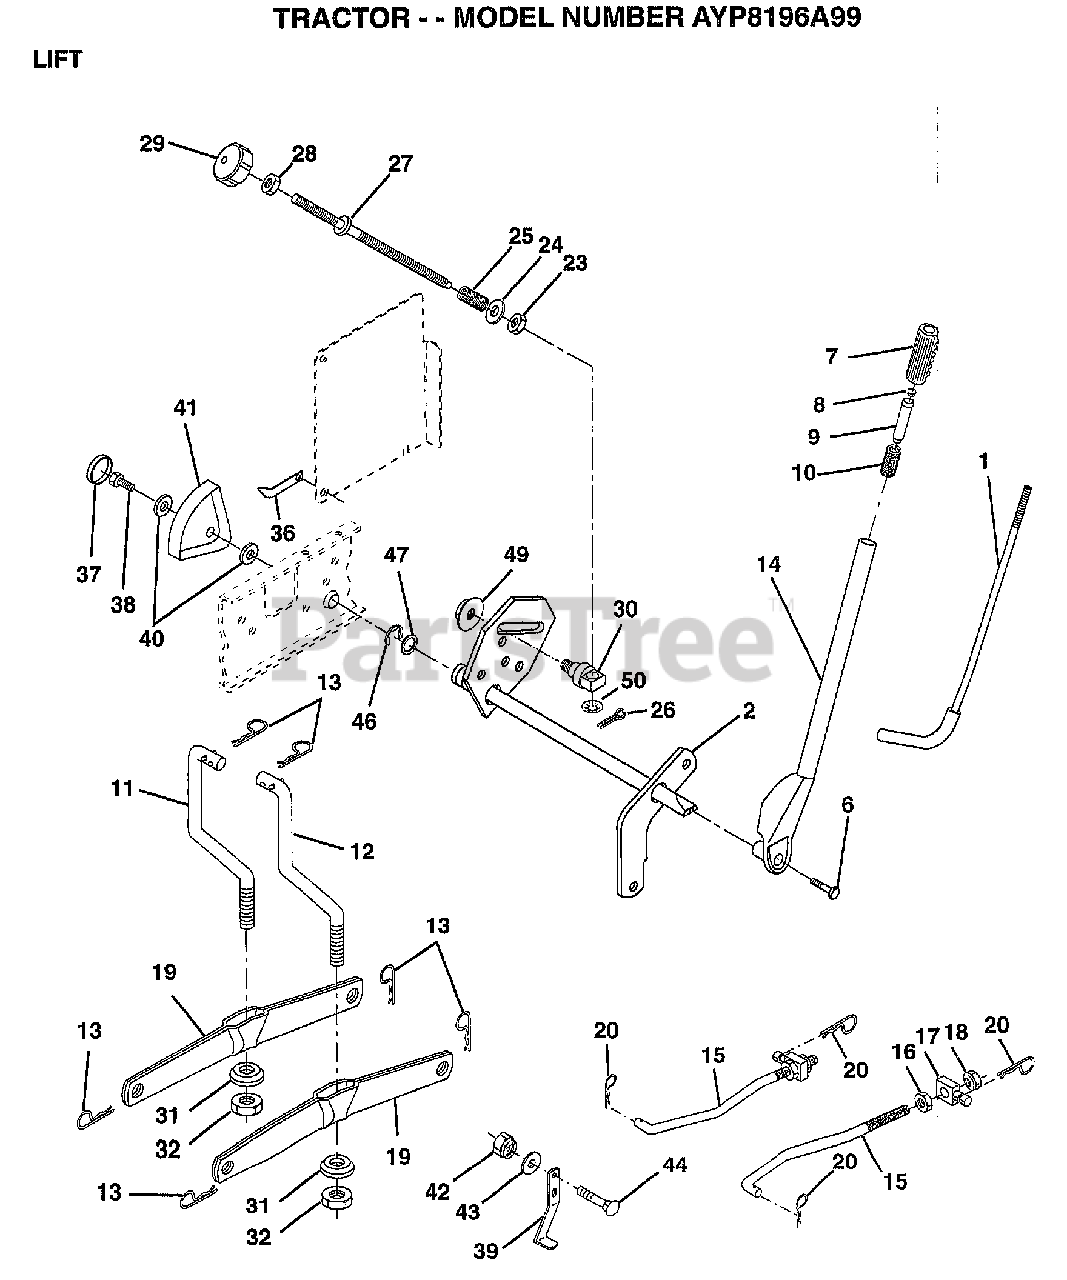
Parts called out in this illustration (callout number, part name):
1	LEVER ROD LT
2	LEVER ASSY LIFT.RH.
6	"BOLT,HEX"
7	GRIP
10	SPRING T
11	LINK.LIFT.LH.GTV
12	LINK.LIFT.RH.GTV.
14	LEVER.ASM.LIFT.RH
15	LINK.FRONT
16	NUT
17	TRUNION
18	NUT LTV
19	ARM SUSP REAR
20	RETAINER SPRING
23	NUT T
24	WASHER
25	SPRING T
28	NUT
29	KNOB INF 3/8-16
30	TRUNNION
31	BEARING PVT LH
32	NUT.CROWNLOCK.3/8
36	POINTER-INDICAT
37	"PLUG,HOLE"
38	SCREW
39	STOP.OVER.CENTER
40	WASHER
41	HEIGHT INDICATOR
43	WASHER GT
44	BOLT
46	E-RING
47	WASHER
49	NUT.HXFLG.LOCK.
50	NUT PUSH M
